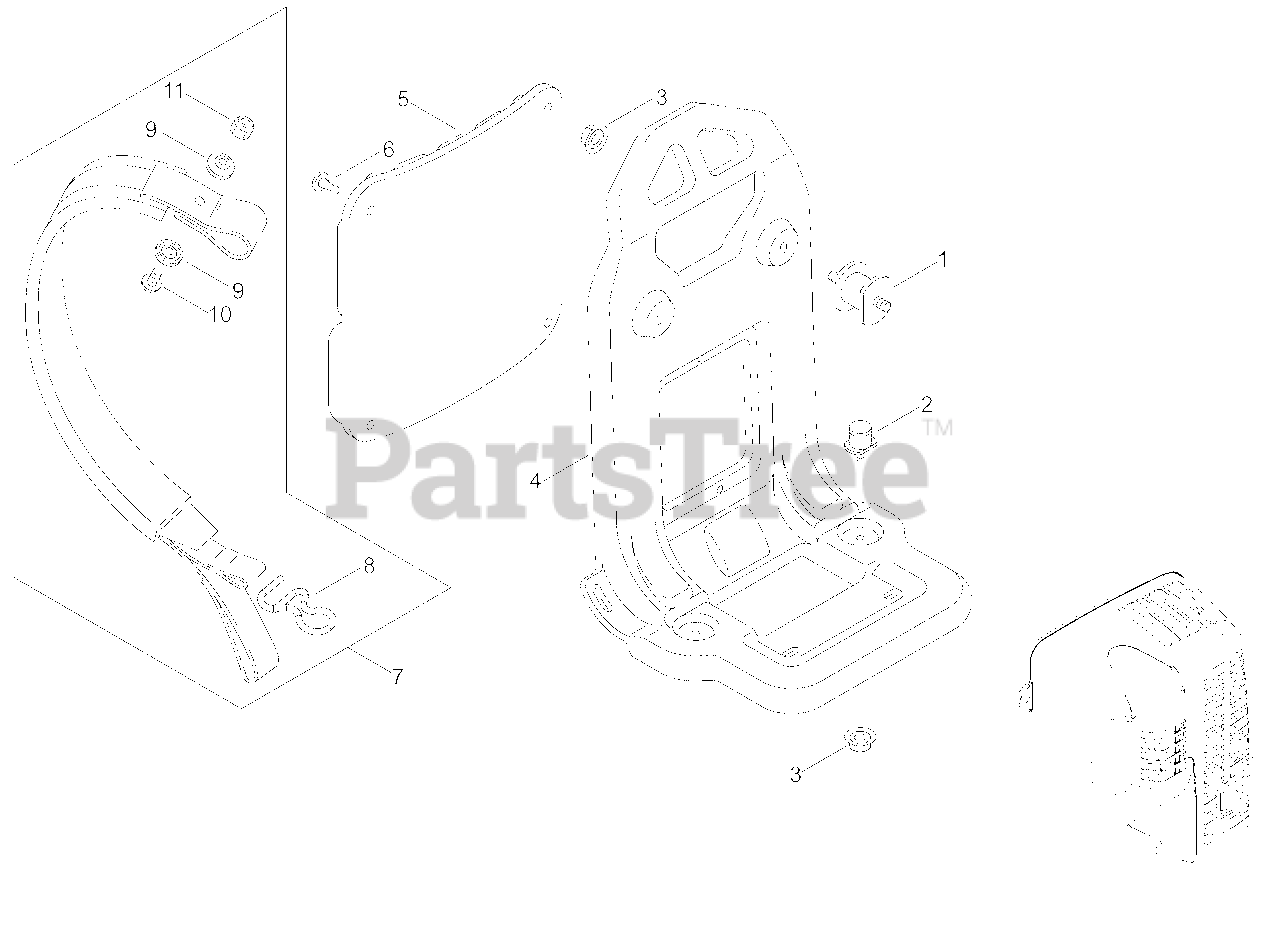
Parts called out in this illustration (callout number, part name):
1	CUSHION 6
2	CUSHION 6
4	FRAME, BACKPACK
5	CUSHION, BACKPACK
7	HARNESS ASSY, BACKPACK
8	RING, HARNESS
9	WASHER 5.2×22×2.0
10	SCREW 5×16
11	NUT, LOCK M5
